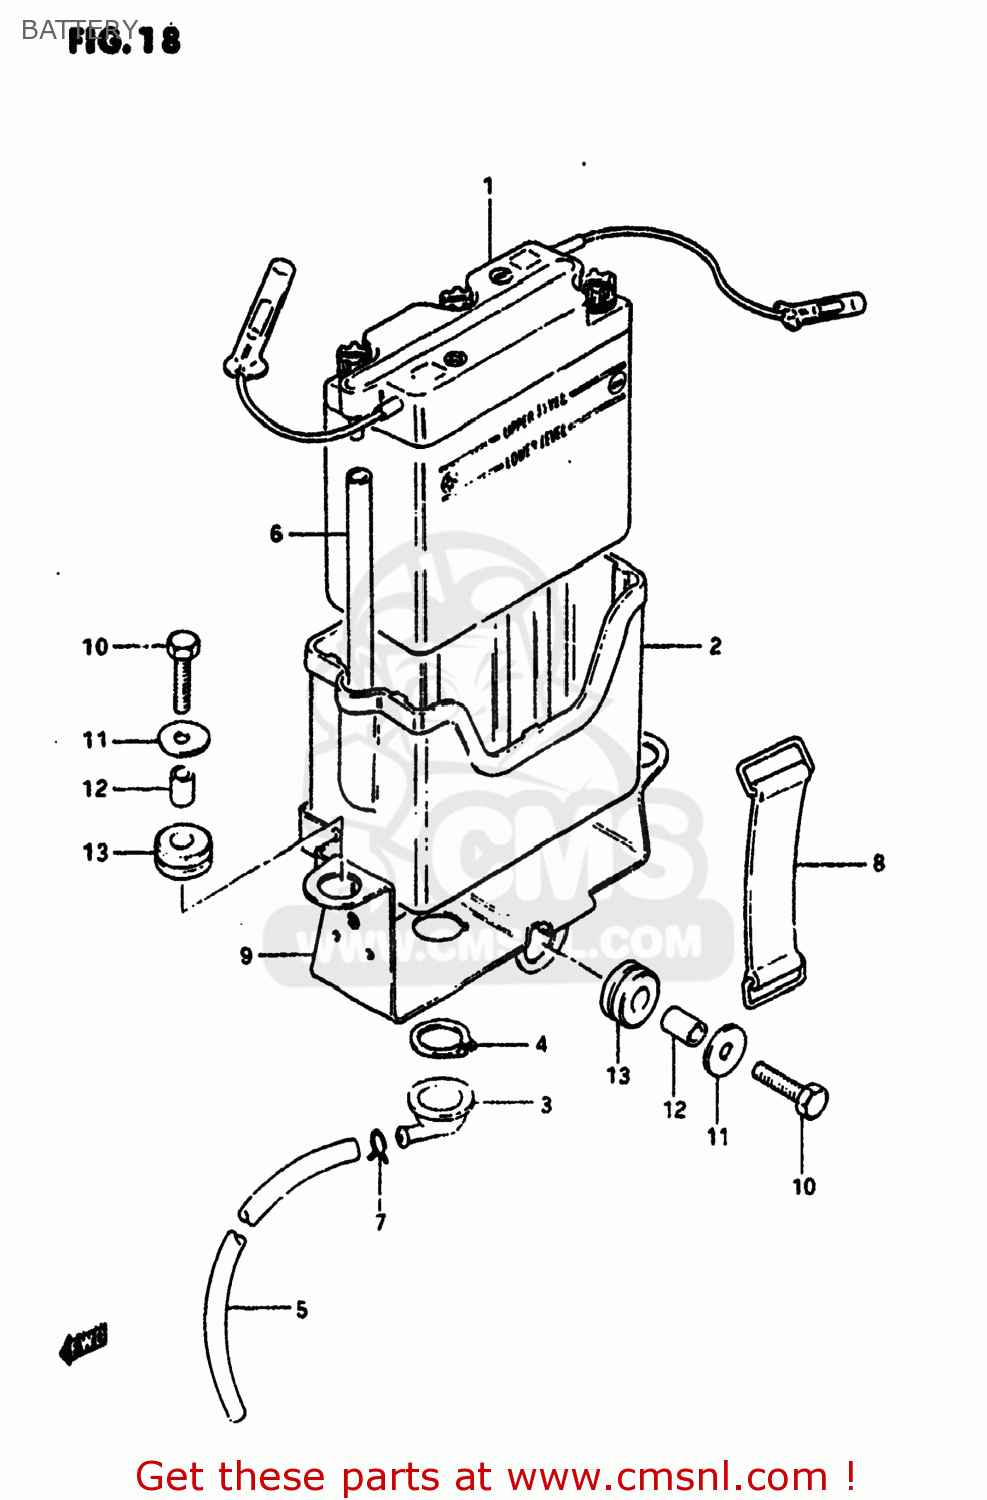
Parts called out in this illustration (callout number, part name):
1	BATTERY ASSEMBLY
2	CASE,BATTERY
3	FUNNEL,BATTERY EXHAUST
4	CIRCLIP
5	HOSE,BATTERY EXHAUST
6	HOSE, EXHAUST (L:45)
7	CLIP
8	BAND
9	HOLDER,BATTERY
10	BOLT, UPPER
11	WASHER (6.5X20X1.2)
12	SPACER(6.1X9X7.5)
13	CUSHION
